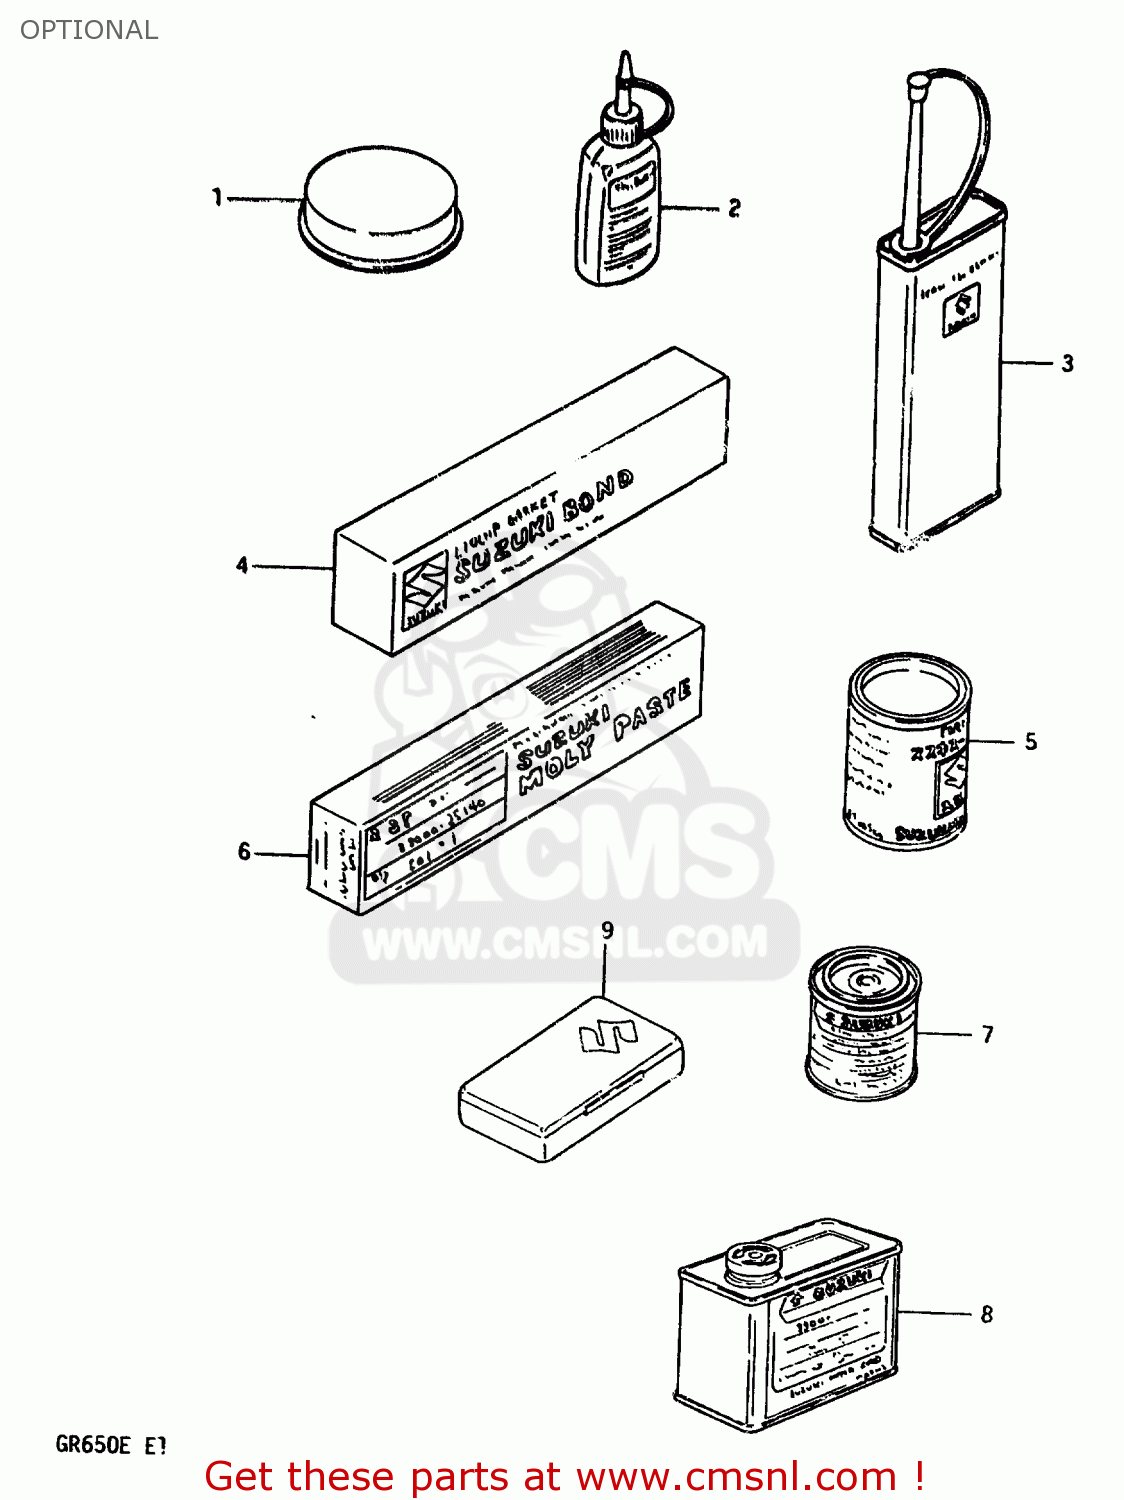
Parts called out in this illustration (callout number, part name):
1	GREASE,PBC FOR BRK PAD 20G
2	THREAD LOCK NO.1342
3	THREAD LOCK NO.1401 CLEAR 200G
4	LIQUID GSKT NO.1207B 100G BLK
5	GREASE(C)EP2 LITHIUM 150G
6	SUZUKI MOLY PASTE
7	PAINT,BLACK
8	PAINT (BLACK)
9	TUBE REPARING TOOL
